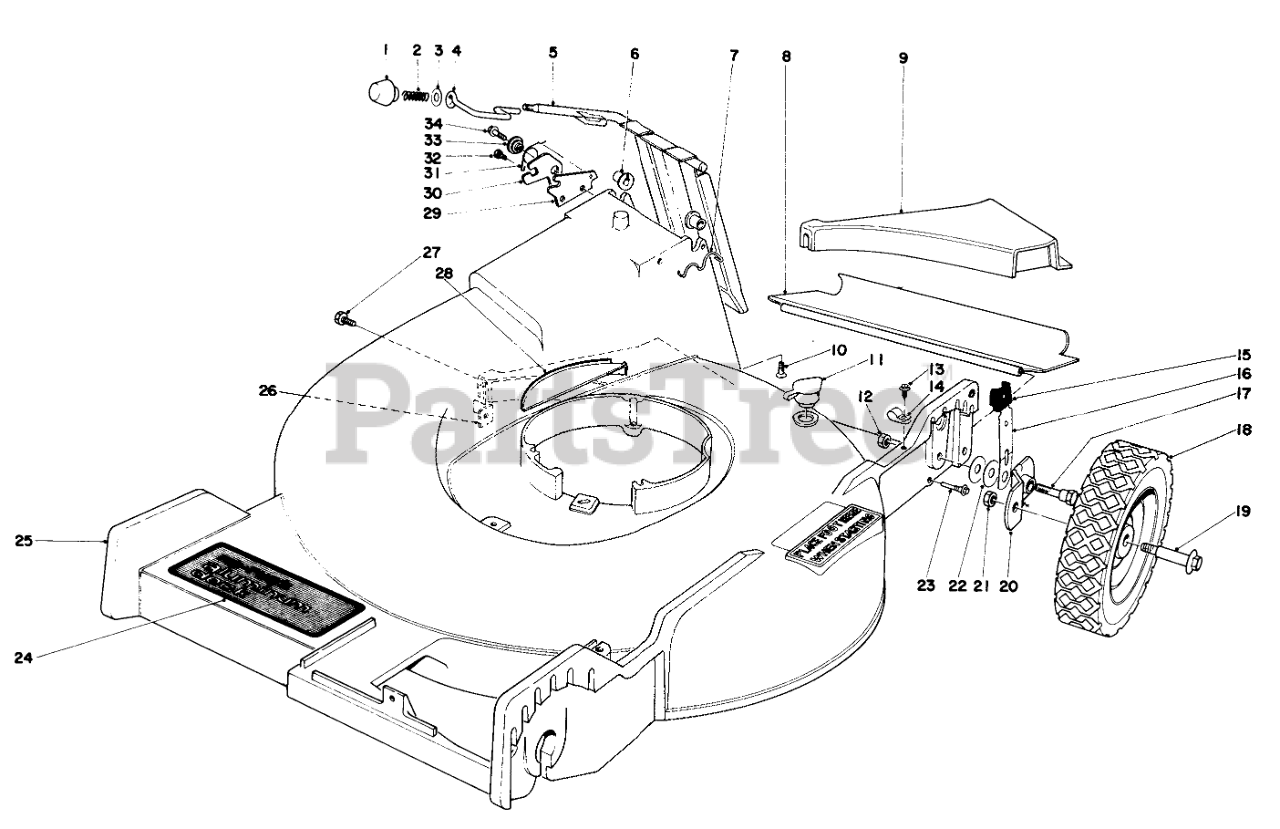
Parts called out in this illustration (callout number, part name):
2	COMPRESSION SPRING
3	WASHER
4	DOOR LATCH
5	Door Handle
6	BUSHING-NYLON
7	Door Retainer
8	REAR SAFETY SHIELD
9	Insert Rear
10	SCREW-HH
11	WASHOUT PLUG
12	Nut
13	SCREW
14	CLAMP-NYLON
15	KNOB-ARM
16	SPRING ARM ASM
17	PIVOT SCREW
18	Wheel Assembly
20	PIVOT ARM ASM A
21	Nut
22	WASHER-PIVOT
23	SAFTEY SHIELD SCREW
24	Decal-Front Housing SP
25	Housing
26	SPECIAL NUT
27	SCREW THD 1/4 20 5/8
28	HOUSING CAP
29	DOOR LATCH PLATE
30	Latch Safety
31	TORSION SPRING
32	SCREW-HWH
33	Latch Spacer
34	Screw
